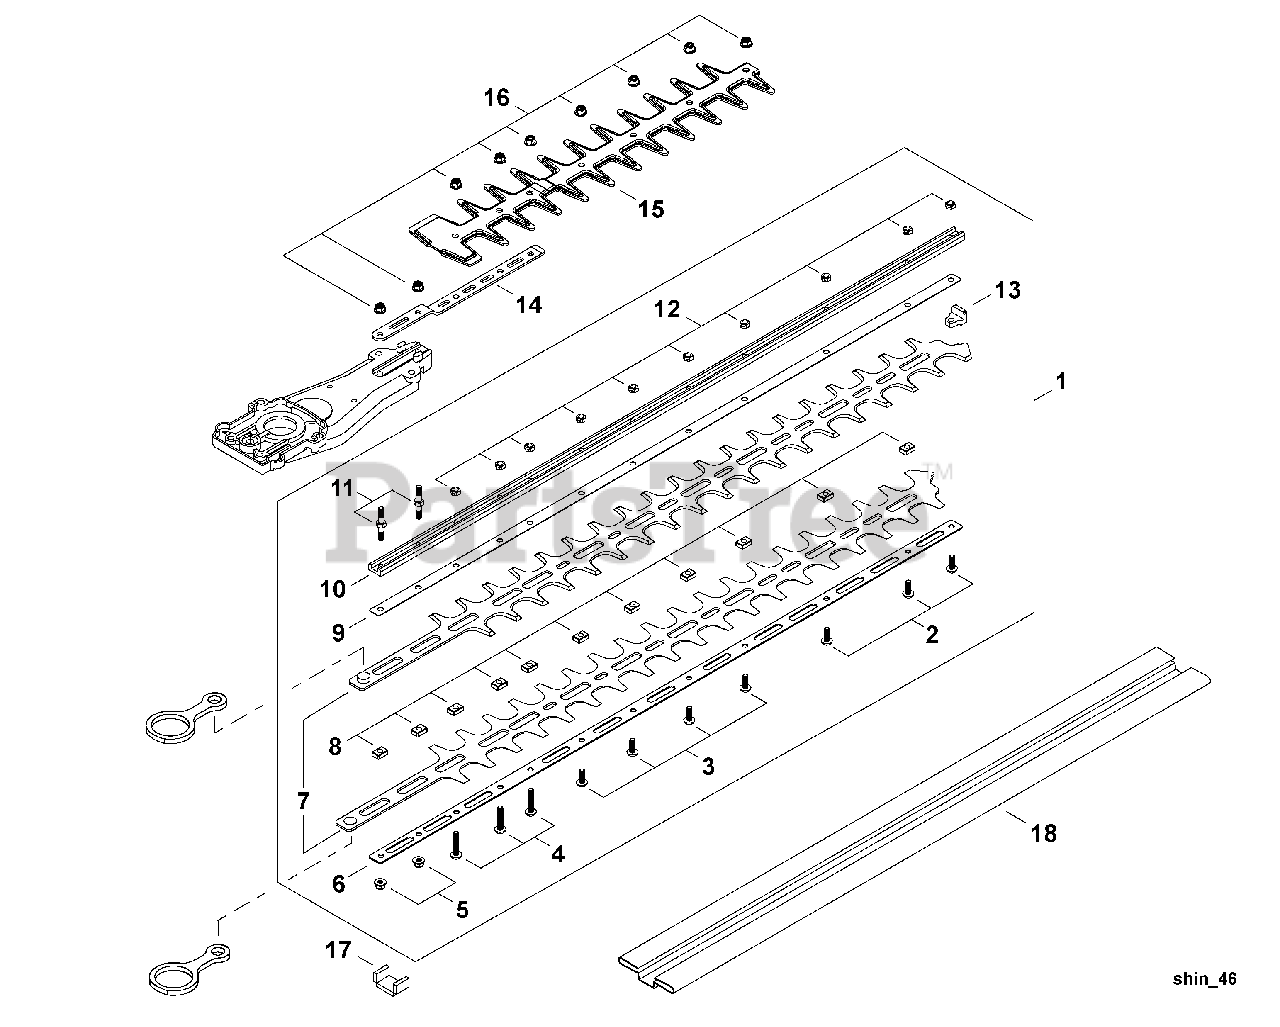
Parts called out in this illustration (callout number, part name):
1	BLADE KIT - 30" (76cm)
2	SCREW - 5X14
3	SCREW - 5X22
4	SCREW - 5X25
5	NUT - 5
6	PLATE - LOWER
7	BLADE - 30" (76cm)
9	PLATE - UPPER -- 30" (76cm)
10	SUPPORT, BLADE - 30" (76cm)
12	LOCKNUT - 5
13	GUIDE, BLADE
14	PLATE, ANGLE
15	SUPPORT, BLADE
16	NUT - 5
17	SEAL, FELT
18	COVER, BLADE - 30" (76cm)
